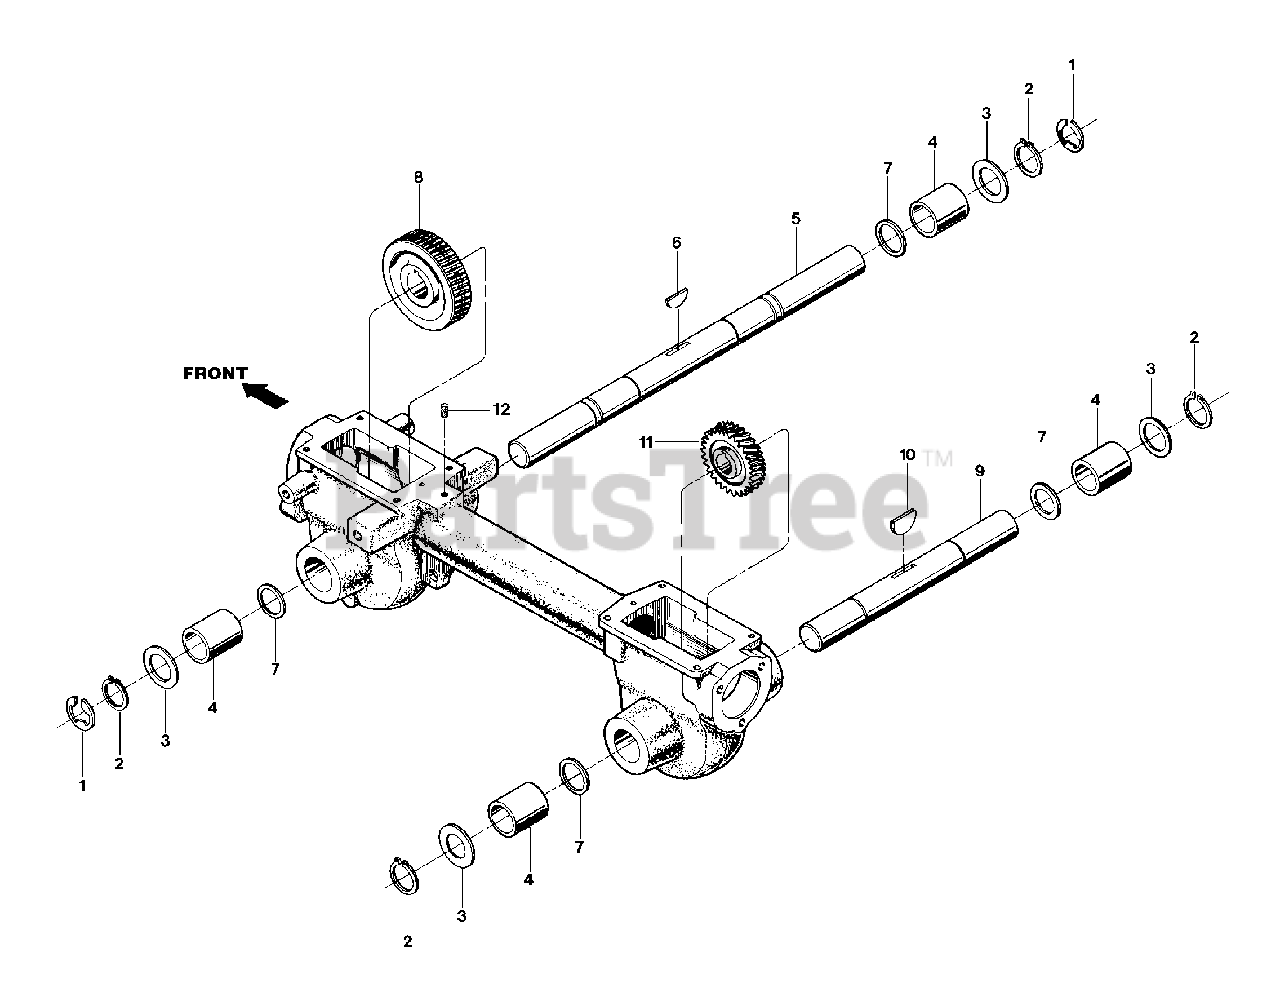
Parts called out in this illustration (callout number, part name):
1	Retainer, Snap Ring, "E" Type
2	Retainer, Snap Ring
3	Shim, 0.062" Thick
4	Bushing, Bronze
5	Wheel Shaft
6	Key, Hi Pro, 1/4 x 1
7	Spacer
8	Worm Gear, Wheel Shaft
9	Tiller Shaft
10	Woodruff Key, Tiller Shaft
11	Worm Gear, Tiller Shaft
